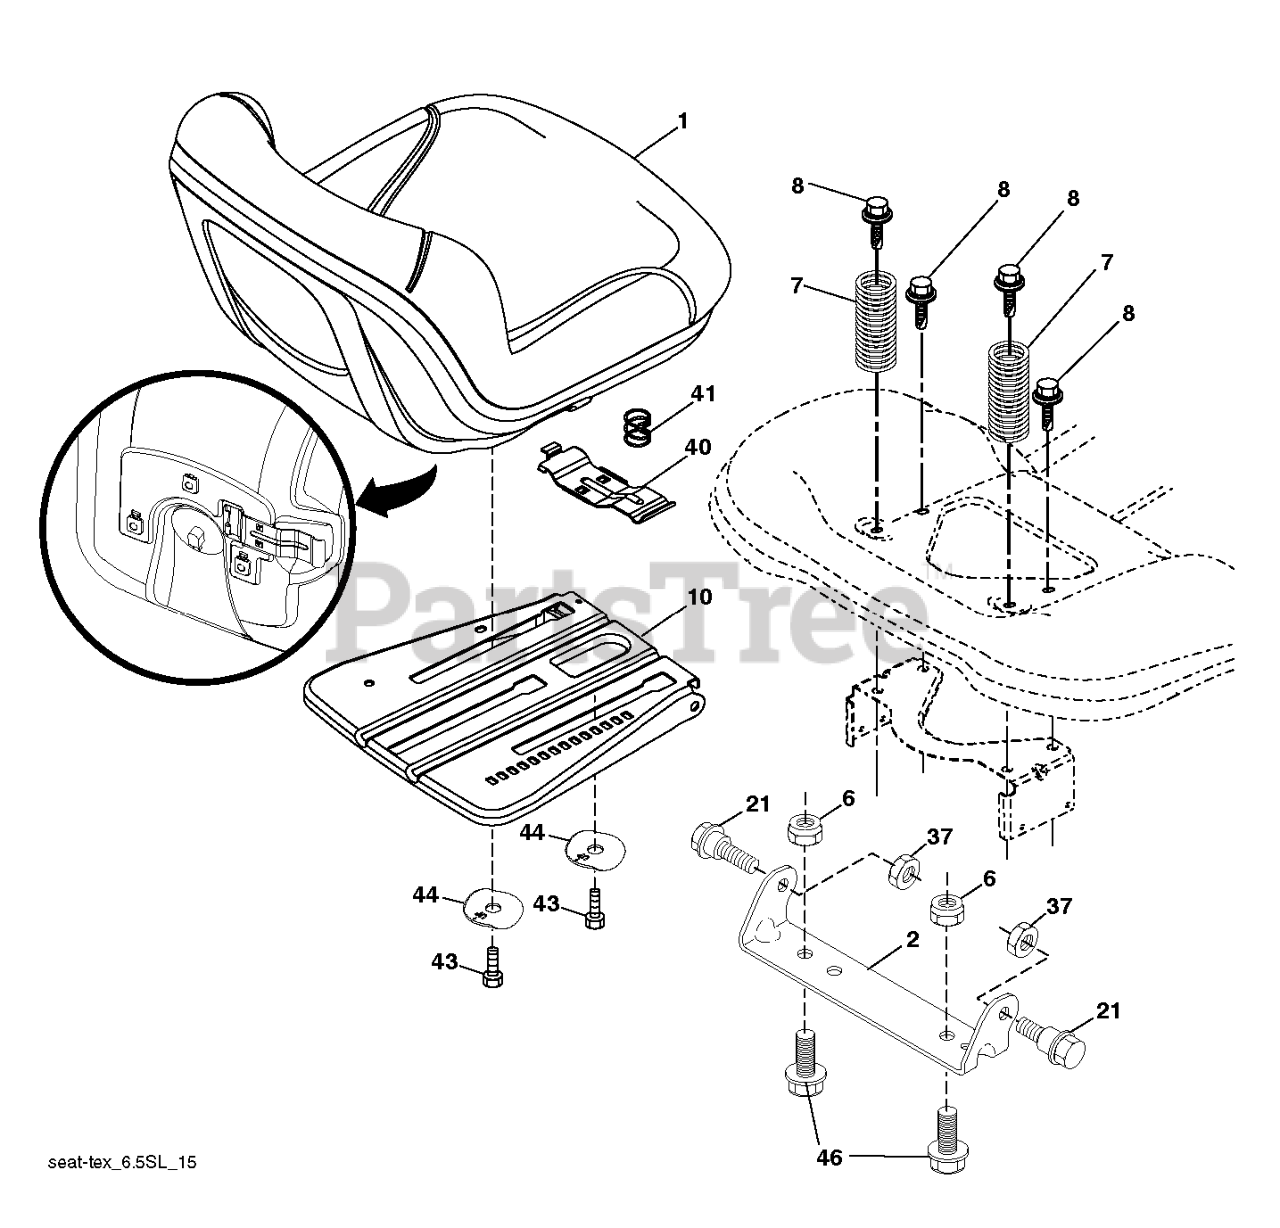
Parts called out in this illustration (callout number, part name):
1	SEAT.TH150.MS498.GRY.HUSQ.TEX
2	BRKT.PIVOT.FENDER
6	NUT
7	SPRING.COMPRESS.SEAT.TAPERED
8	BOLT.5/16-18UNCX3/4 W/SEMS.BLK
10	PLATE SEAT; SLIDE; 3PT BLACK;
21	BOLT.5/16-18X5/8.SHOULDER
41	SPRING.LATCH.SEAT.TEX
44	WASHER.WINGED.3/8ID.1.5OD
46	BOLT.3/8-16X1;1.25OD.WSHR.SEMS
